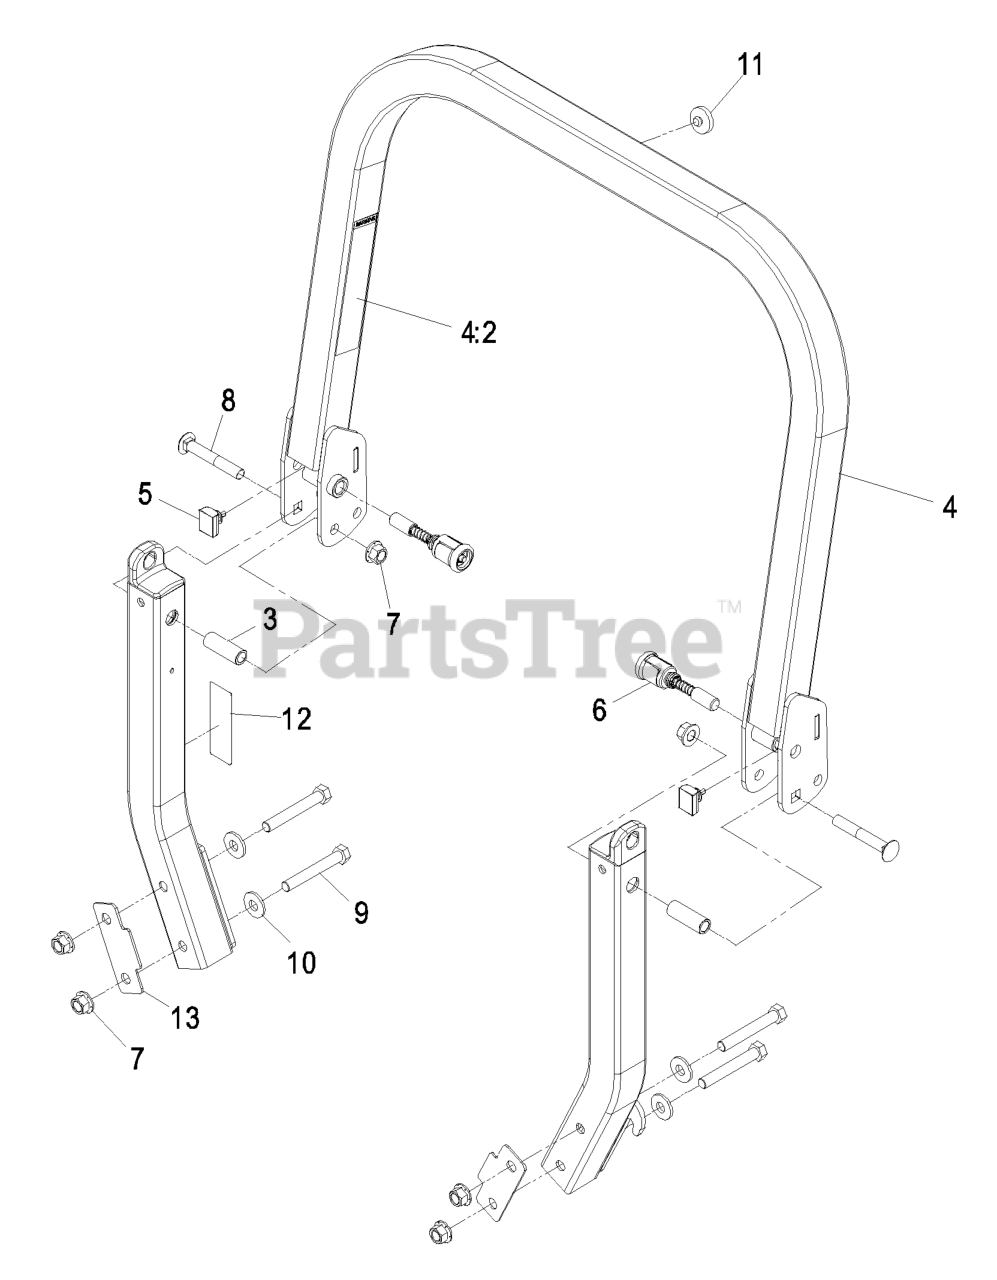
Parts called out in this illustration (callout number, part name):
4	UPPER ROPS ASM
4:2	DECAL-WARNING, FOLDING RO
5	BUMPER-ROPS
6	PIN-SPRING
7	Nut-Lock 1/2-13
8	SCREW-CARR
9	SCREW-HH
10	WASHER-SPRING
11	BUMPER-PUSH-IN, RUBBER
12	DECAL-CAUTION
